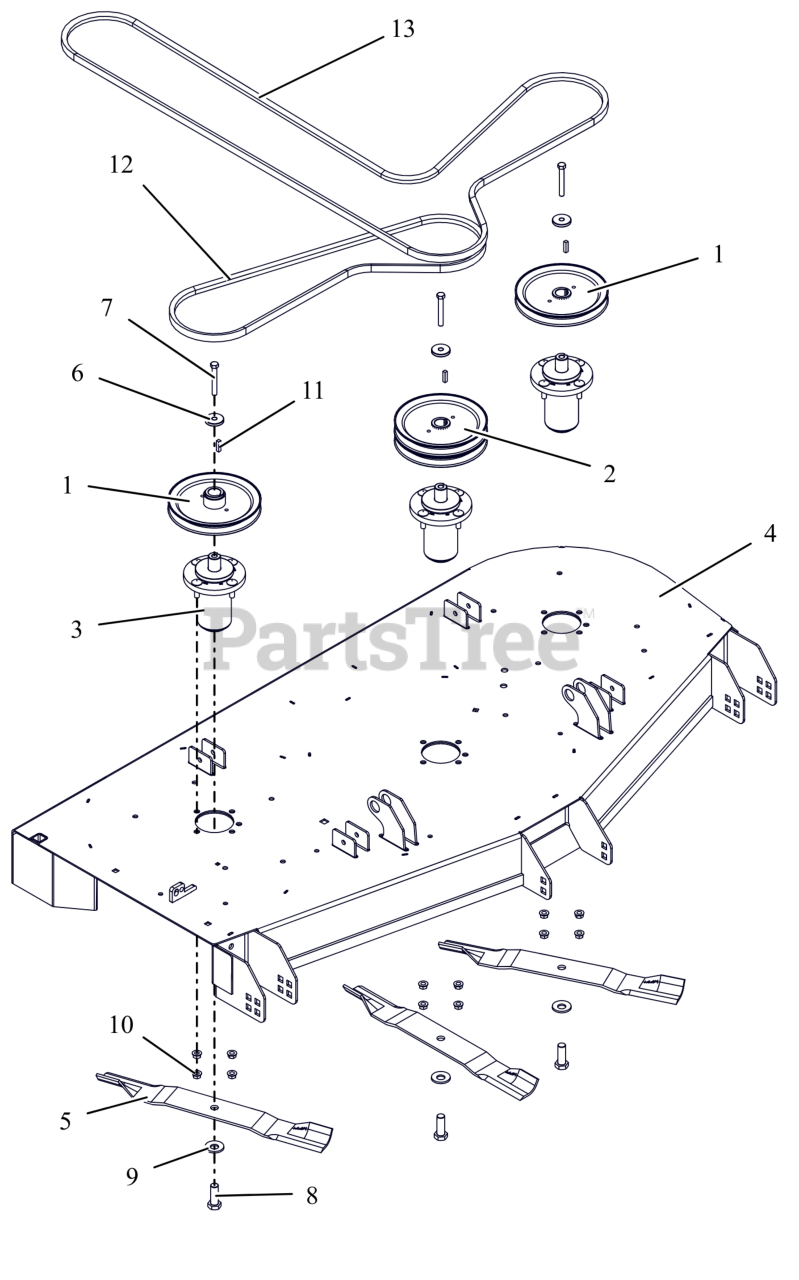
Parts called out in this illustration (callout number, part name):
1	PULLEY- V-7.50 OD X 1" ID
2	PULLEY- DOUBLE-1"X7.50"&7.50"
3	ASM, MAINT FREE ALUM SPINDLE
4	KIT,DECK-60" W/DECALS -APEX LE
5	BLADE, 20.5"
6	RETAINER, SHEAVE
7	BLT, HEX .38-16X2.75 G8 ZCC
8	BLT, HEX .62-18X1.75 G8 ZCC
9	WSHR-BLVL .669X1.535X.138
10	NUT-LK-CTR-FLG .375-16 GF ZCC
11	KEY, SQ .25X.25X1.00 RC 40-50
12	V-BELT, B-COGGED
13	V-BELT, HB SECTION
